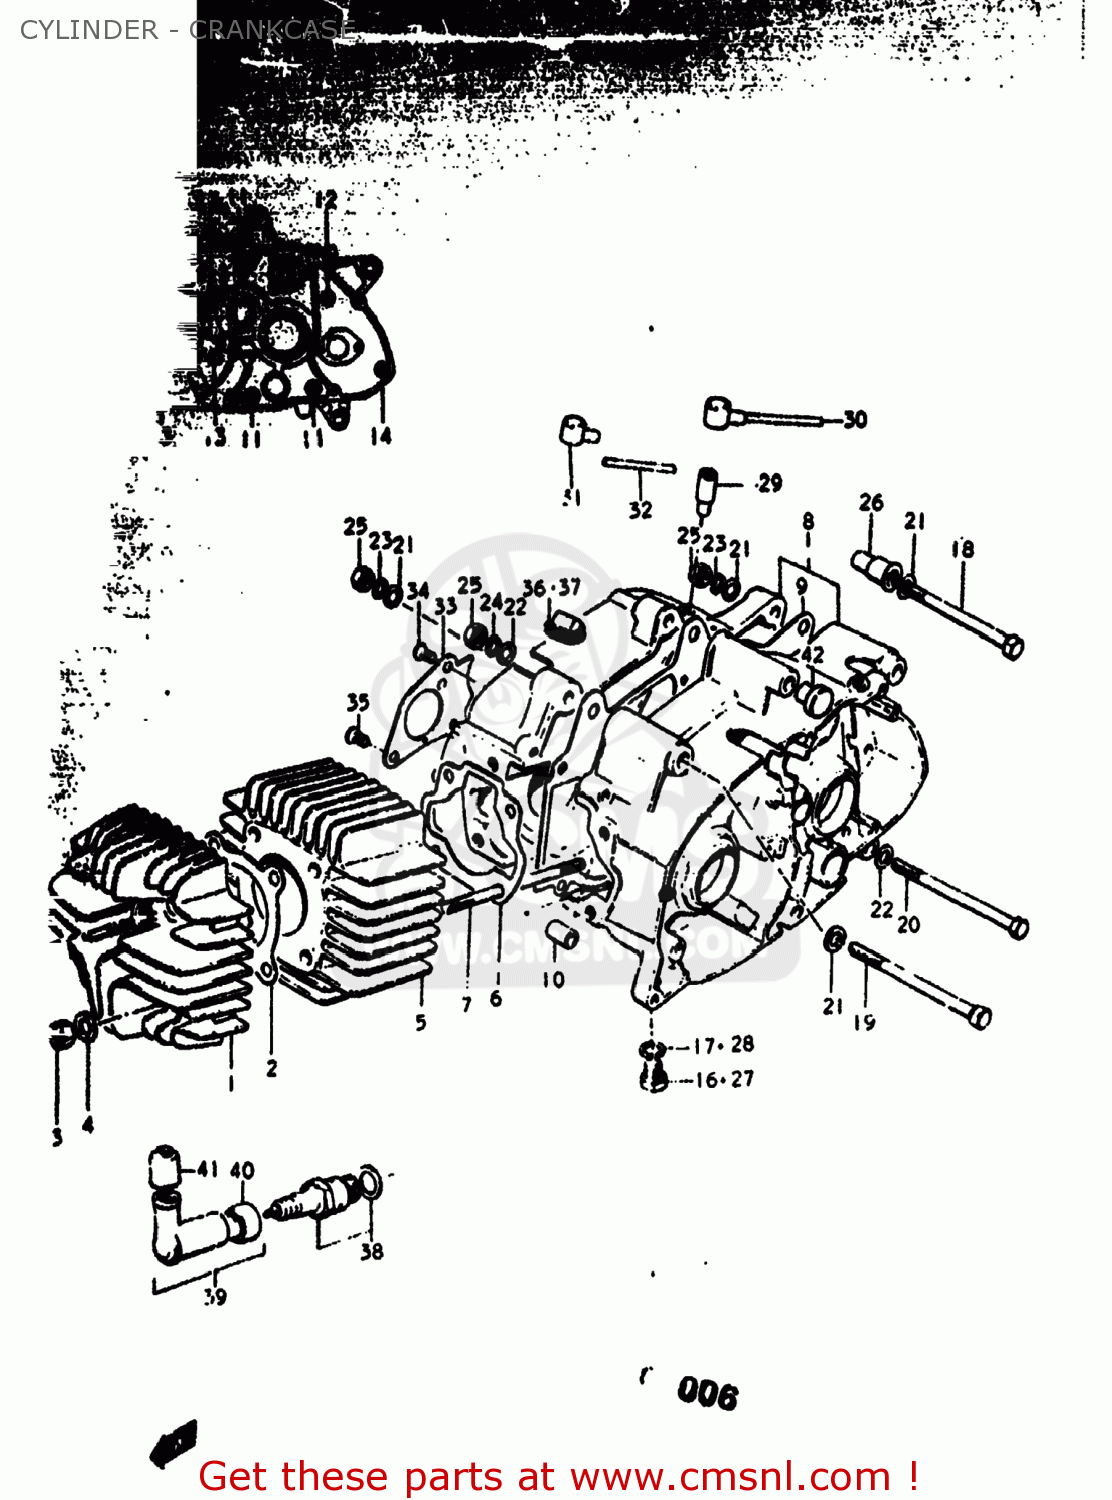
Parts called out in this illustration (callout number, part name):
1	HEAD,CYLINDER
2	GASKET,CYLINDER HEAD (NAS)
3	NUT (8MM)
4	WASHER
5	CYLINDER
6	GASKET,CYLINDER (MCA)
7	BOLT,STUD
8	CRANKCASE SET
9	GASKET,CRANKCASE (MCA)
10	PIN
11	SCREW 6X70
12	SCREW
13	SCREW (6X45)
14	SCREW (6X35)
15	SCREW
16	PLUG
17	GASKET(10X14X3.6) (NAS)
18	BOLT 8X100
19	BOLT 8X110
20	BOLT
21	WASHER
22	WASHER
23	LOCK WASHER
24	WASHER,LOCK,8.
25	NUT
26	BUSH
27	PLUG
28	GASKET(14X19.2X2) (NAS)
29	PLUG,TRANSMISSION BREATHER
30	PLUG,BREATHER
31	GASKET (NAS)
32	HOSE
33	PLATE,OIL RESERVOIR
34	SCREW
35	SCREW 6X12
36	GROMMET
37	GROMMET
38	SPARK PLUG
39	CAP,SPARK PLUG
40	SEAL,SPARK PLUG
41	SEAL,SPARK PLU
42	CAP
